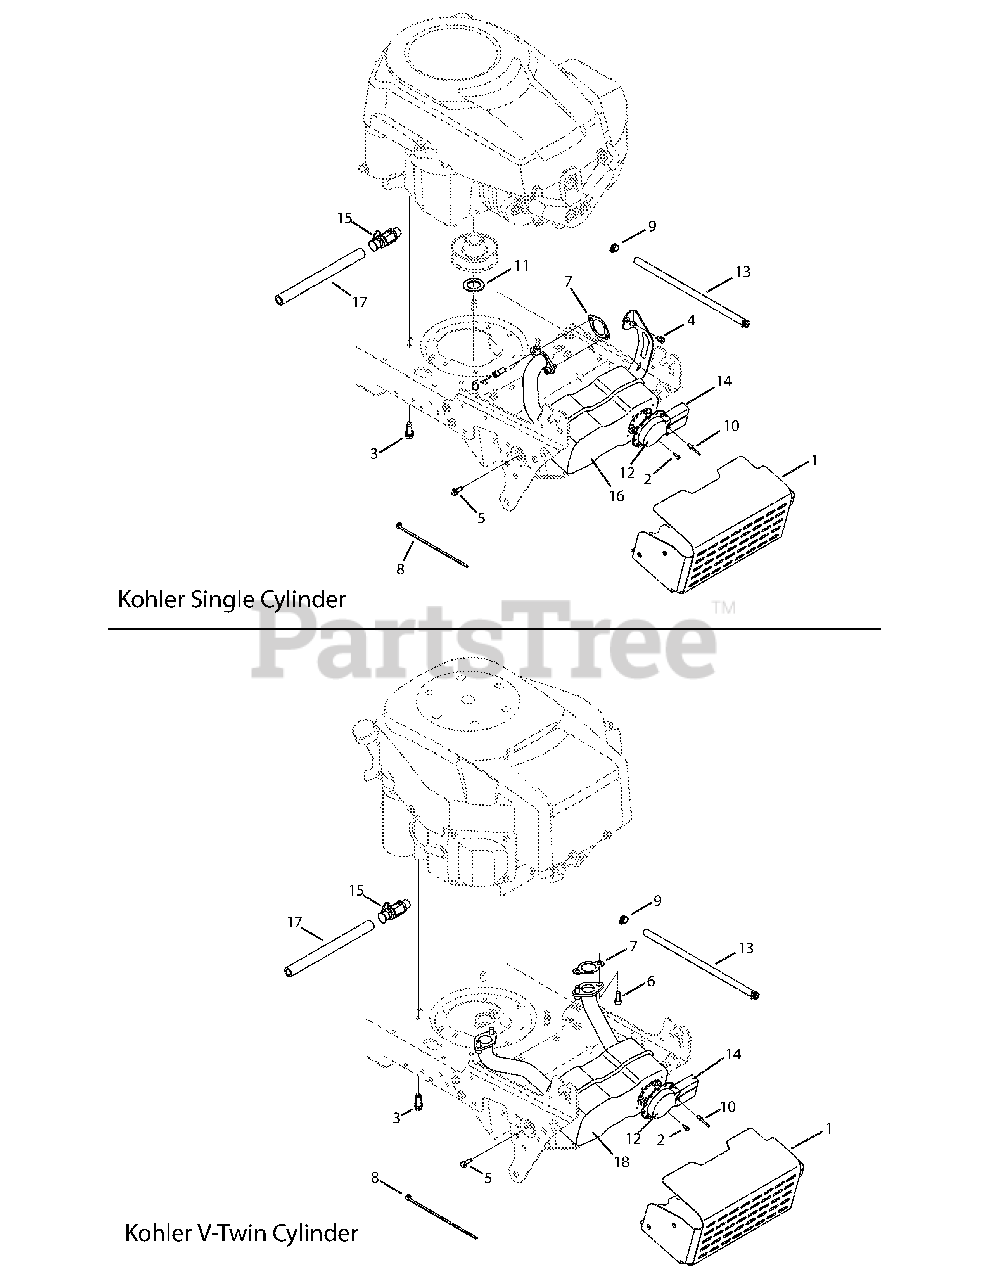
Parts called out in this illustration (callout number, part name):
2	Screw, #8-18, 0.500
3	Screw, Hex, 3/8-16 x 1.00
4	Screw, Hex, 1/4-20, 0.500
5	Screw, Hex, 1/4-20, 0.750
6	Screw, 5/16-18, 0.75
7	Exhaust Gasket
8	Cable, Tie, 3/16 x .05 x 7.4
9	Hose Clamp
10	Rivet, Pop, .188 x .325
11	Flat Washer, 1.031 x 1.620 x .095
12	Deflector, Muffler
13	Fuel Line, Low Permeation
14	Extension, Deflector
15	Drain, Oil
16	Muffler, Single Inlet
17	Extension Hose, Oil Drain
18	Twin Muffler, Kohler
19	Self-Tap Screw, M5 x 0.8 Torx
20	Conduit Dual Clamp, Kohler
